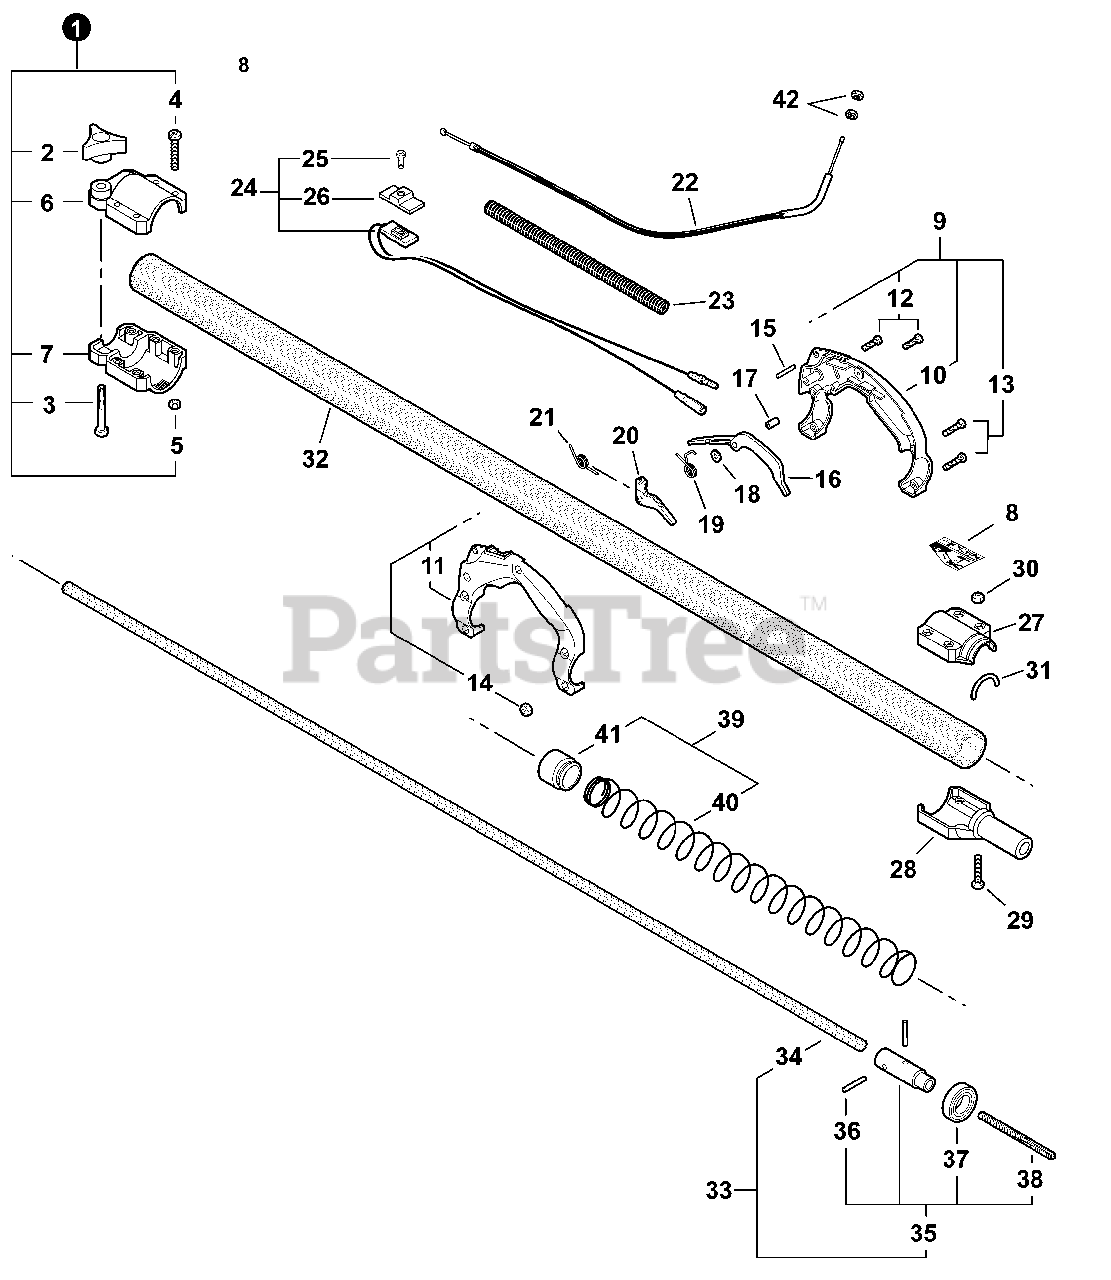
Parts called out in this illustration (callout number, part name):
1	CLAMP ASSY
2	THUMBSCREW
4	SCREW, TORX 10-24 UNC 1-1/4
5	NUT, LOCK 10-24 UNC
6	COLLAR, UPPER
7	COLLAR, LOWER
8	LABEL, CAUTION - ELECTRICAL
9	HANDLE SET, REAR
10	HANDLE, LEFT REAR
11	HANDLE, RIGHT REAR
12	SCREW, TORX 10-24 UNC 1-1/4
13	SCREW, TORX 10-24×1.5
14	NUT, LOCK 10-24 UNC
15	PIN, LOCATING .17 OD. × .75 L
16	LOCKOUT, THROTTLE
17	COLLAR 5.08×14.5
18	WASHER 5.5×12×0.8
19	SPRING, TORSION 0.39 I.D.
20	TRIGGER, THROTTLE
21	SPRING, TORSION
22	CABLE, THROTTLE
23	TUBE, FLEXIBLE
24	SWITCH, ON-OFF
25	SCREW 3×10
26	KNOB, SWITCH - ORANGE
27	CAP, MAIN PIPE
28	ADAPTER, LOWER DRIVE SHAFT
29	SCREW, TORX 10-24×1.5
30	NUT, LOCK 10-24 UNC
32	PIPE, MAIN 1.5 ID×60" L
33	SHAFT ASSY, DRIVE
34	DRIVESHAFT
35	CONNECTOR, DRIVE SHAFT
37	BEARING, BALL 6002 DDU
39	BUSHING ASSY, FLOATING
40	SPRING, COMPRESSION
41	BUSHING, FLOATING
